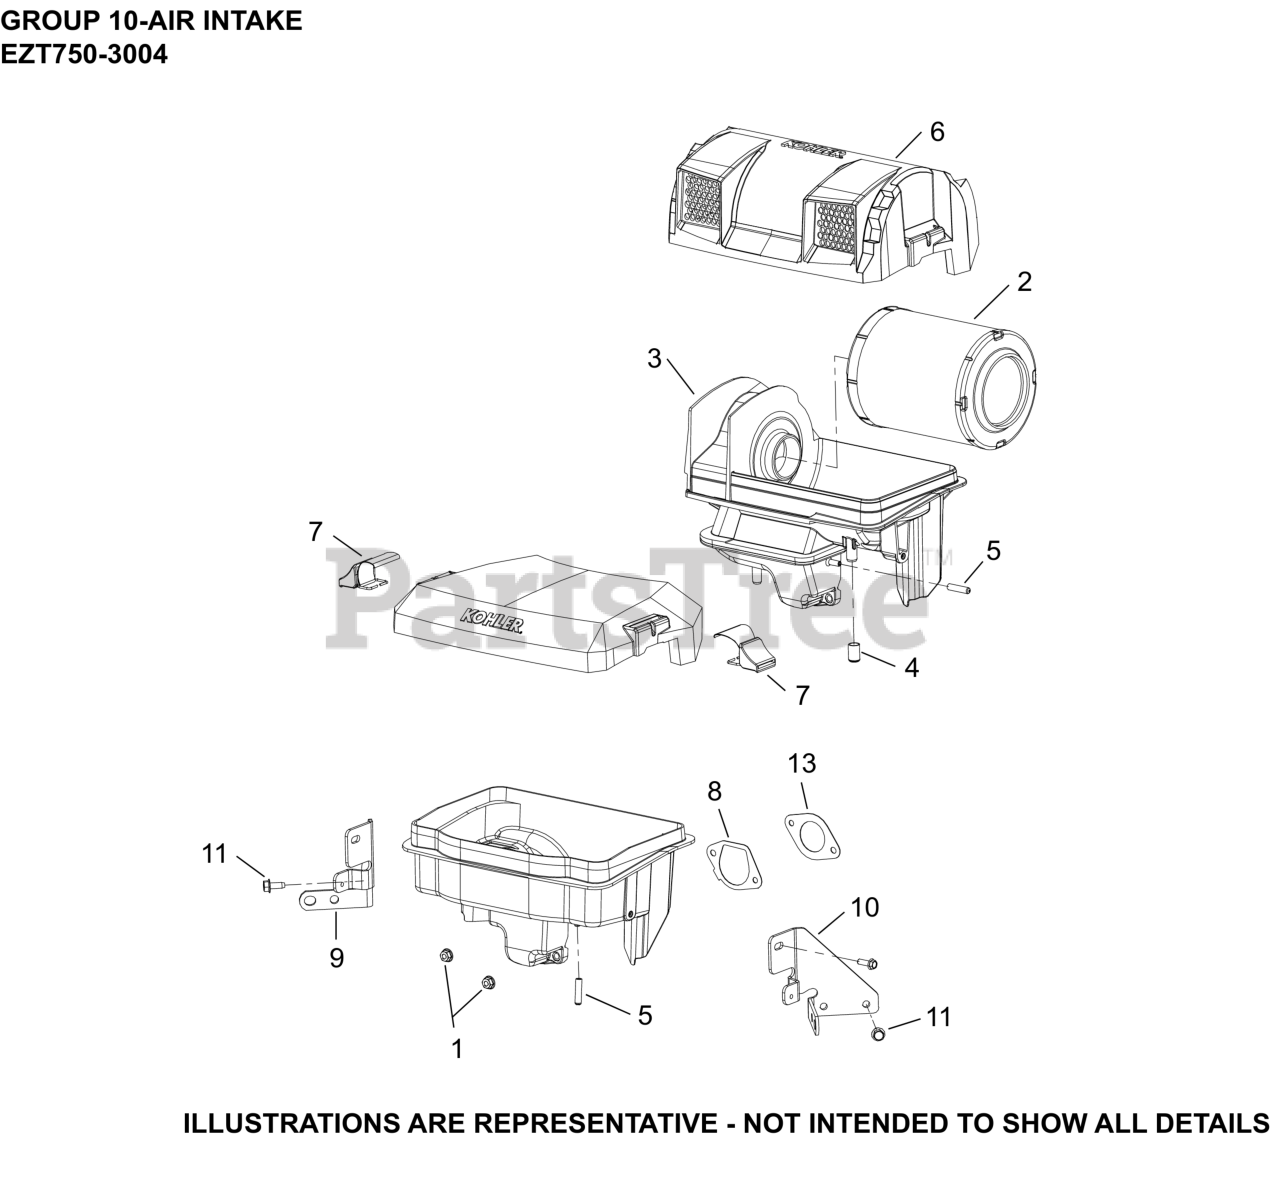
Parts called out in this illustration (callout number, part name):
1	NUT, FLG M6X1.0
2	ELEMENT, AIR FILTER
3	BASE ASSEMBLY, AIR CLEANER (HDAC)
4	CAP, MASKING
5	CAP, MASKING
6	COVER, AIR CLEANER (HDAC)
7	LATCH ASSY, AIR CLEANER COVER
8	GASKET, AIR CLEANER BASE
9	BRACKET, AIR CLEANER BASE (#1 SIDE)
10	BRACKET, AIR CLEANER BASE (#2 SIDE)
11	SCREW, THREAD FORMING
13	GASKET, THROTTLE BODY
NI	ELEMENT, PRE-CLEANER
NI	SCREW, HI-LOW
